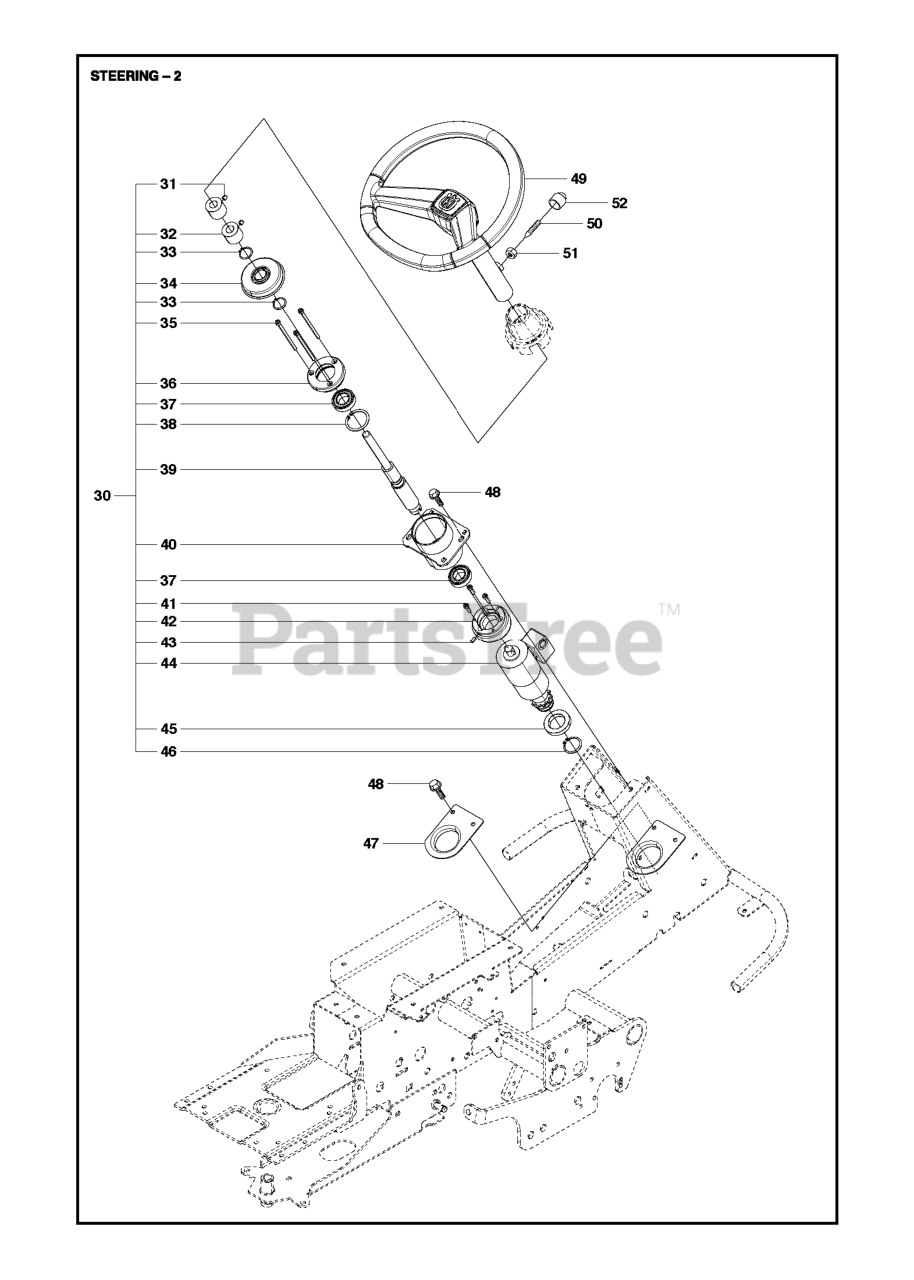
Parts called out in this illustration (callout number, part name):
32	SPACER
33	RETAINING RING SGA 25
35	SCREW IHSCM.
37	Ball Bearing 6005-2rs
38	CIRCLIP SGH 47
41	SCREW MC6S 6X20
43	SPRING PIN
44	COMFORT STEERING
51	NUT
52	PROTECTIVE COVER
